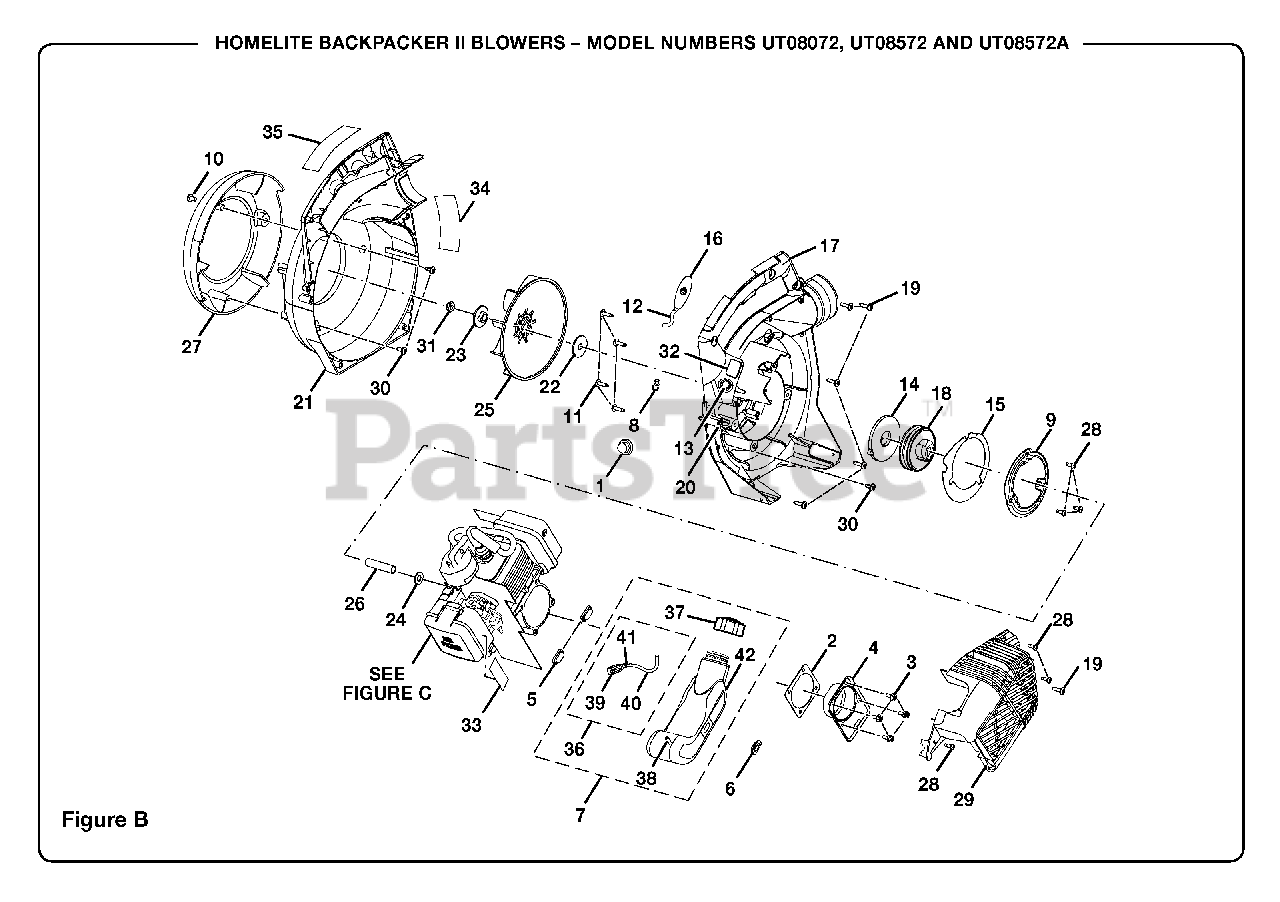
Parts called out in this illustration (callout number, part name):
1	PRIMER BULB
2	CRANKCASE GASKET
3	SCREW (10-24 x 9/16 in. PAN HD.)
4	CRANKCASE COVER
5	RUBBER BUMPER
6	BIG BUMPER
7	FUEL TANK ASSEMBLY
8	BUSHING-STARTER ROPE
9	BAFFLE PLATE
10	SCREW (1/4-20 X 3/4)
11	SCREW (10-24 x 3/4 in. TRUSS HD.)
12	STARTER ROPE
13	BUSHING STARTER
14	SPRING & CONTAINER
15	BAFFLE GASKET
16	STARTER GRIP
17	INNER VOLUTE HOUSING
18	PULLEY ASSEMBLY
19	SCREW (10-14 x 3/4 in. TORX TRUSS HD.)
20	SCREW (10 x 1-5/8 in. HEX HD.)
21	OUTER VOLUTE
22	FLAT WASHER
23	FAN ADAPTOR
24	FLAT WASHER
25	FAN
26	FAN SPACER
28	SCREW (#8 x 1/2 in. PAN HD.)
29	BLOWER SHROUD
30	SCREW (10-24 x 3/4 in. TORX TRUSS HD.)
31	NUT (3/8-24)
32	SWITCH COVER LABEL
33	CHOKE LABEL
34	FAN INTAKE WARNING LABEL
35	WARNING/STARTING LABEL
36	FUEL FILTER KIT
37	FUEL CAP ASSEMBLY
38	RUBBER TUBING (196.85 mm)
39	FUEL FILTER
40	RUBBER TUBING (114.3 mm)
41	WIRE CLAMP
42	FUEL TANK
